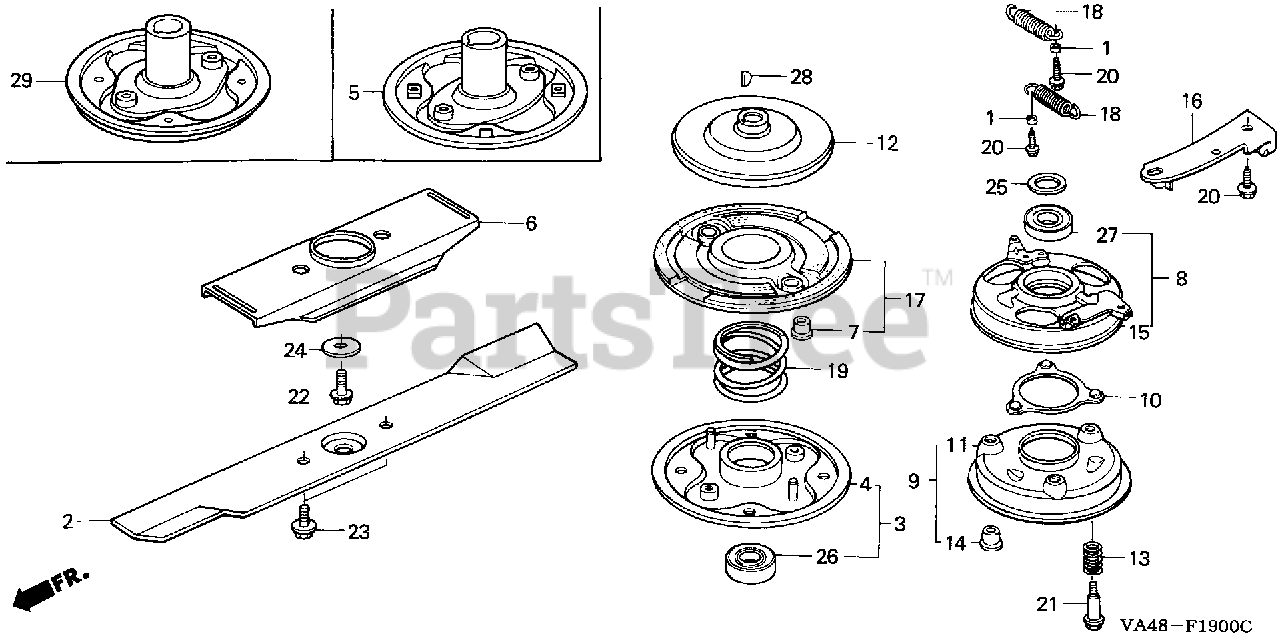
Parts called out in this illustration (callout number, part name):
2	BLADE, ROTARY (21")
5	HOLDER, BLADE
6	HOLDER, BLADE
22	BOLT, HEX. (10X25)
23	BOLT, HEX. (10X20)
28	KEY, WOODRUFF (16X15)
29	HOLDER, BLADE
